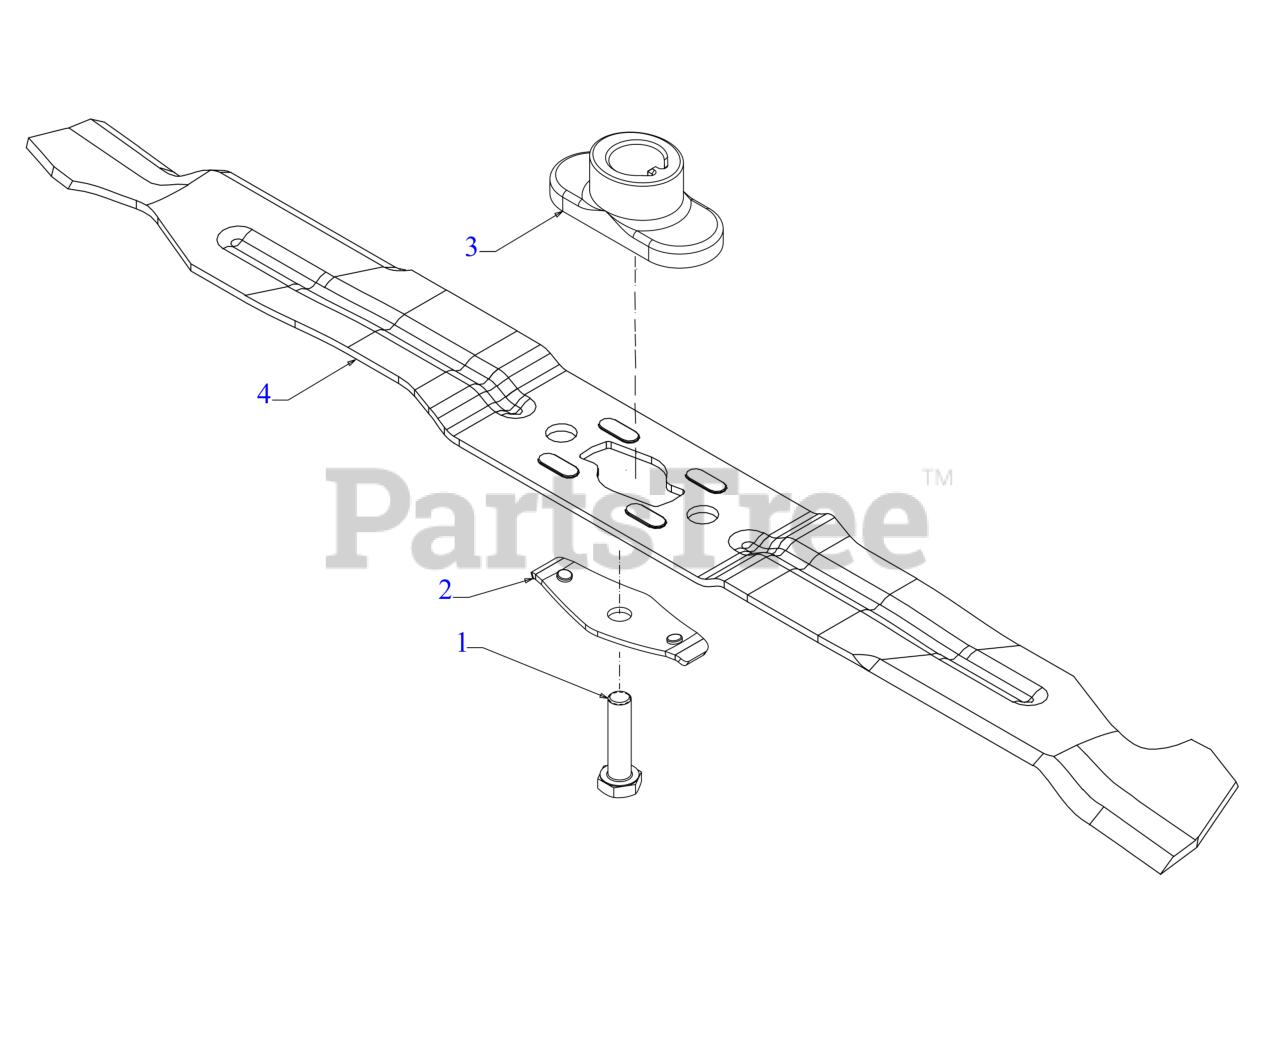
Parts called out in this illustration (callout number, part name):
1	SCREW 3/8-24 x 1.50 GR8
2	BLADE BELL SUPPORT
3	BLADE ADAPTER (#6 X 1.19 W/S)
4	21" MULCH BLADE (S SHAPE CENTER HOLE)
